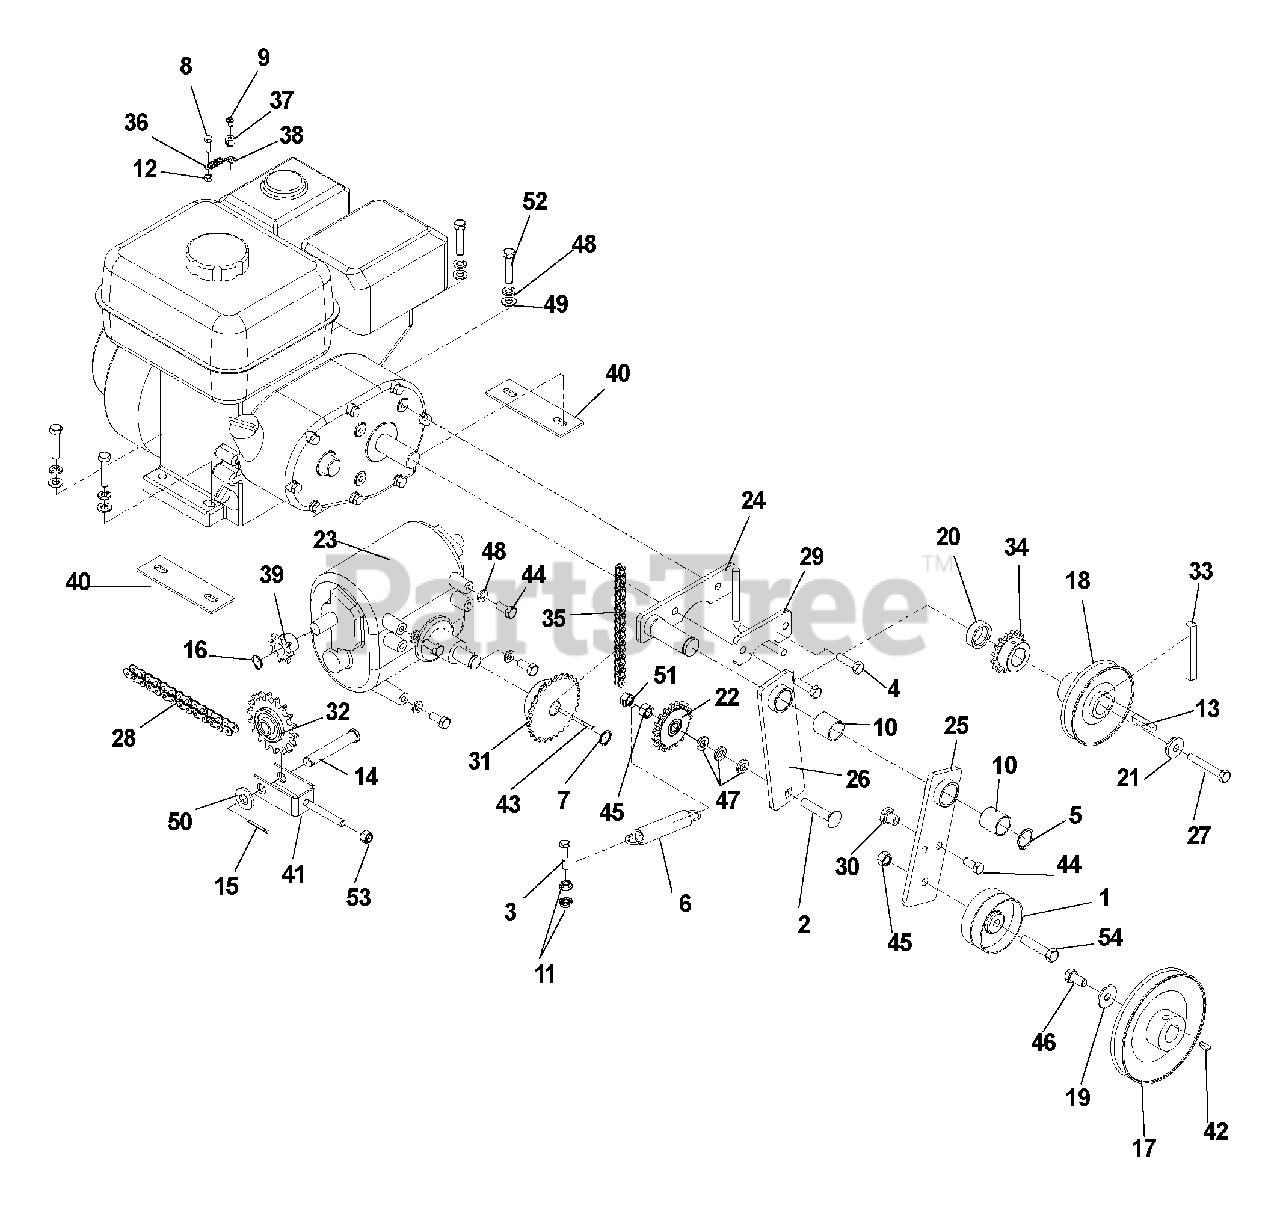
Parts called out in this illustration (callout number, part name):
1	PULLEY, IDLER
2	RHSNB, 3/8-16 X 2, GR5
3	HCS, 1/4-20 X 1 1/4, GR5
4	HCS, M8-1.25 X 30MM, GR8.8
5	RING-RETAINING, EX 7/8
6	SPRING, AXLE AERATOR
7	RING-RETAINING, EXT 5/8
8	HCS, M5-0.8 X 16MM, GR8.8
9	SCREW, METRIC SPECIAL, 1/4
11	NUT, 1/4-20
12	NUT, 5MM-.8
13	KEY, 7MM SQ X 33MM
14	PIN CLEVIS, 1/2 X 3
15	PIN COTTER, 1/8 X 1
16	RING RETAINING, 9/16, EXT
17	PULLEY, 5.25
18	PULLEY, 3.75
19	SPRING, WASHER
20	SPACER, PTO SHAFT
21	WASHER, STEPPED
22	SPROCKET, IDLER 35 PITCH
23	TRANSMISSION, 4 SPEED
24	IDLER PIVOT
26	IDLER, CHAIN
27	HCS, M8-1.25 X 55MM, GR8.8
28	CHAIN, TRANSMISSION, #40
29	KEEPER - CHAIN
30	SPRING ANCHOR
31	SPROCKET TRANSMISSION
32	SPROCKET, CHAIN TENSIONER
33	V-BELT
34	SPROCKET, ENGINE
35	CHAIN, TRANSMISSION #35
36	SPRING, THROTTLE
37	CLAMP, THROTTLE CABLE
38	CLIP, THROTTLE
39	SPROCKET, #40 CHAIN, 8 TOOTH
40	SMALL ENGINE PLATE
41	CHAIN TENSIONER
42	KEY, WOODRUFF #6
43	KEY, WOODRUFF #9
44	HCS, 5/16-18 X 3/4, GR5
45	NUT, 3/8-16, NYLOC
46	HCS, 3/8-24 X 3/4, GR5
47	WASHER, 3/8
48	WASHER, 5/16
49	WASHER, 5/16, SAE
50	WASHER, 1/2, SAE
51	NUT, 3/8-16, CENTERLOCK
52	HCS, 5/16-18 X 1 3/4, GR5
53	NUT, 5/16-18, NYLOC
54	HCS, 3/8-16 X 1 3/4, GR5
